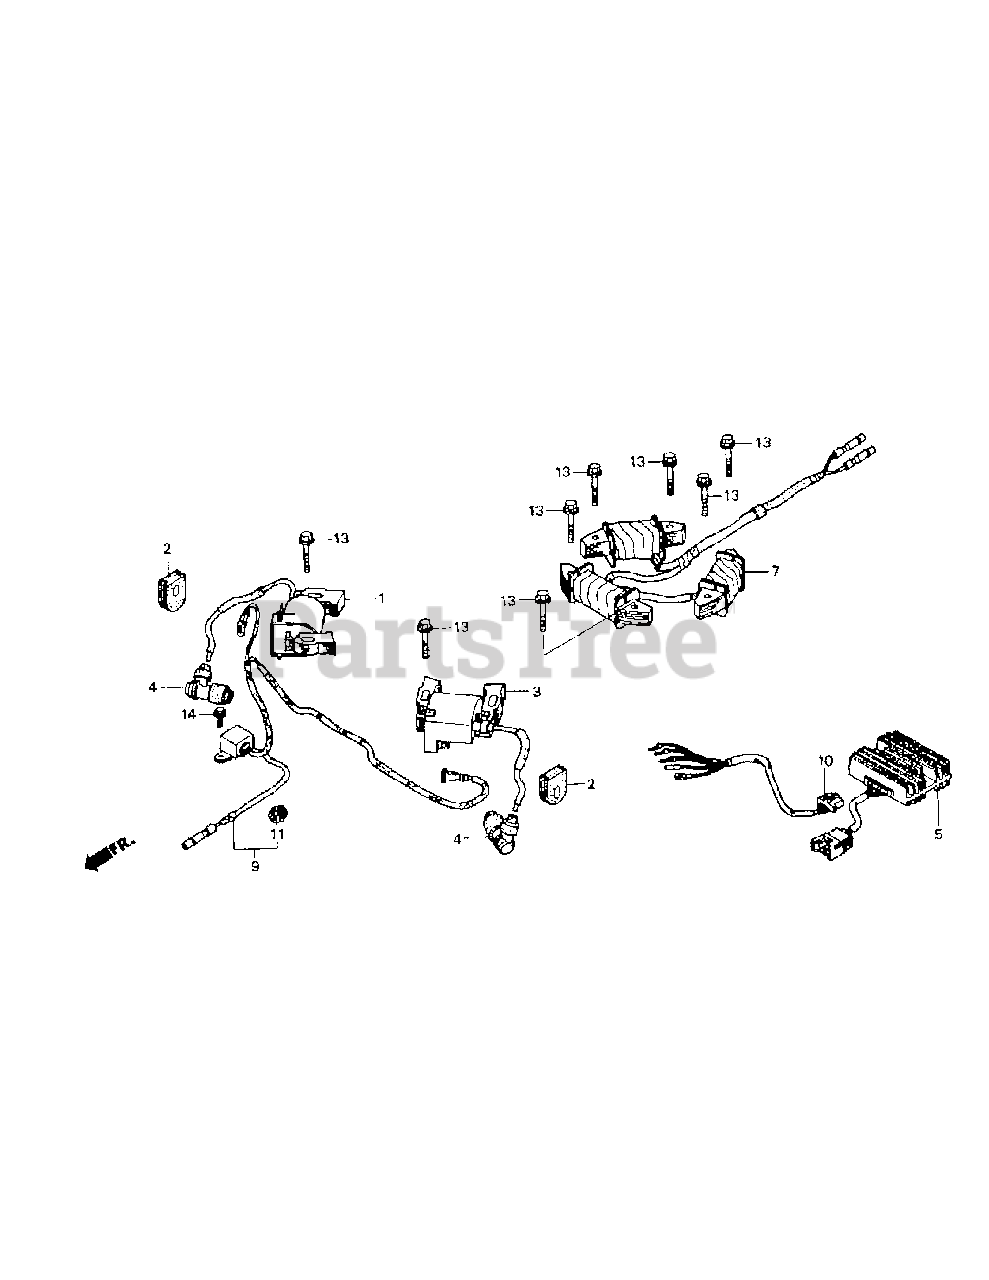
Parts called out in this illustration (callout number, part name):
1	Ignition Coil Assy. R.H.
2	Ignition Wire Grommet
3	Ignition Coil Assy. L.H.
4	Noise Suppressor Cap Assy.
5	Voltage Regulator
7	Stator Assy.
9	Engine Stop Diode Assy.
10	Sub-Wire Harness Assy.
13	Flange Bolt (6x32)
14	Flange Bolt (6x8)
